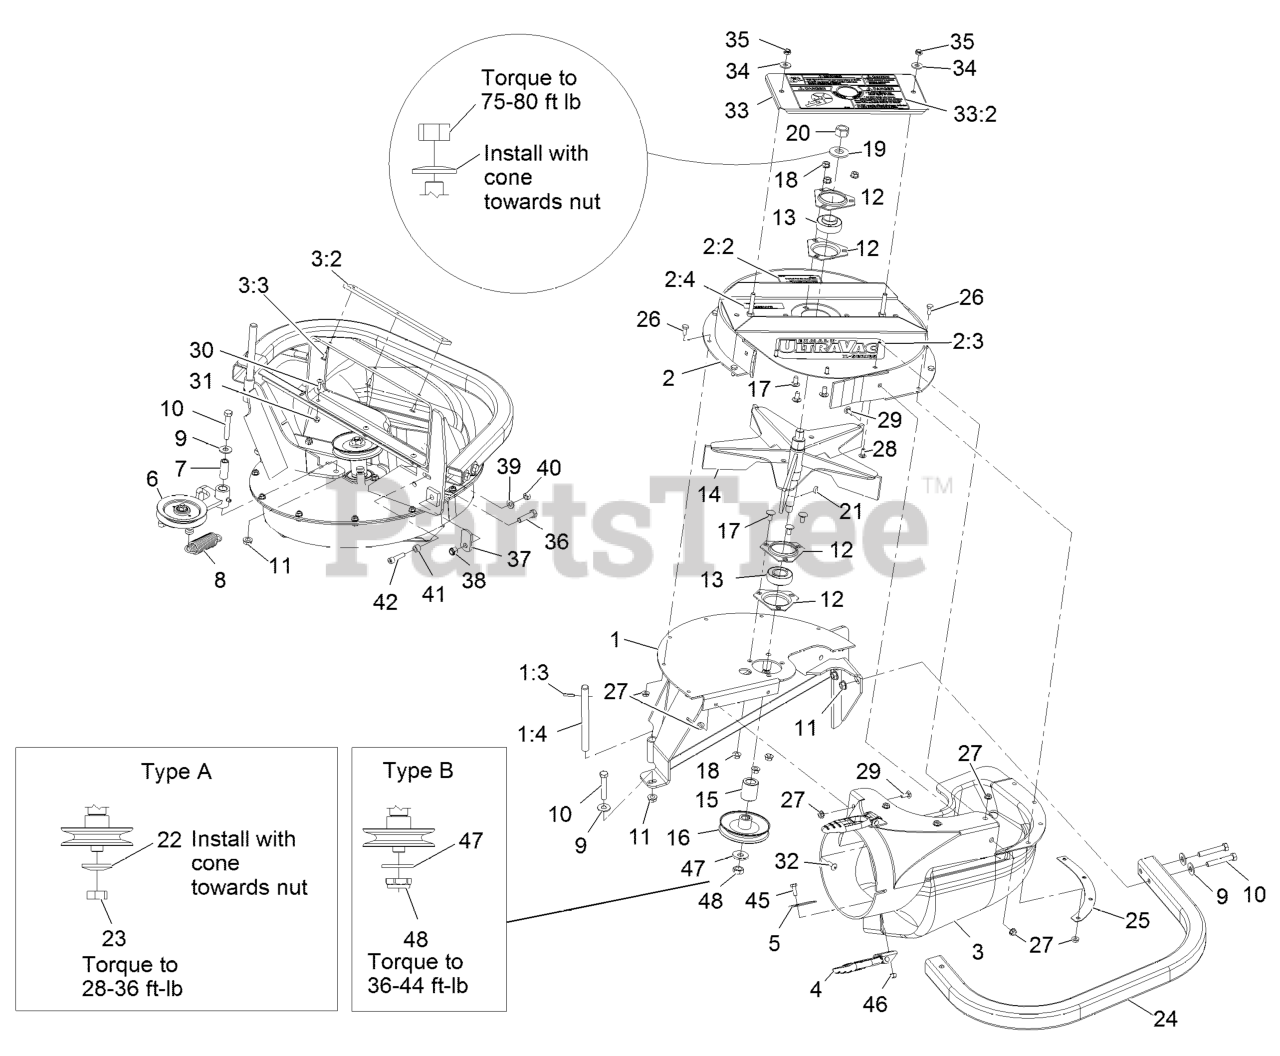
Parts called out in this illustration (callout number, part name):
1	WLD,FRAME LG BLOWER
1:3	PIN-ROLL
1:4	SHAFT-CATCHER, GRASS
2	ASM-UPPER HOUSING LARGE
2:2	DECAL,WEIGHT
2:3	DECAL-ULTRA VAC X-SERIES
2:4	DECAL-COVER, MISSING
3	ASM,BLOWER CHUTE LZ
3:2	PLATE,REINFORCEMENT LARGE
3:3	RIVET-BLIND
4	LATCH-RUBBER
5	PLATE-BACKING
6	Asm, Idler
7	BUSHING
8	SPRING-IDLER
9	WASHER-FLAT
10	SCREW-HH
11	NUT-HHF, WHIZ
12	HOUSING-FLANGE
13	BEARING
14	IMPELLER
16	SHEAVE
17	SCREW-CARR
19	WASHER-SPRING
20	NUT-HEX
21	KEY-WOODRUFF
22	WASHER-SPRING
23	NUT-JAM
25	PLATE-BACKING, BLOWER
26	SCREW-HH
28	SCREW-CARR
29	BOLT-CARR
30	SCREW-HEAD, TRUSS
33	COVER, BEARING
33	ASM, BEARING COVER
33:2	DECAL-WARNING, BLOWER
34	WASHER-FLAT
35	NUT-LOCK, NI
36	SCREW-HH
37	LATCH-CATCHER, GRASS
38	NUT-LOCK, NI
39	WASHER-SPRING
40	NUT-HEX
41	BUSHING, LOCATOR
42	SCREW-HSH
45	SCREW-HH
46	NUT-LOCK, NI
47	WASHER-FLAT
48	NUT-LOCK, NI
